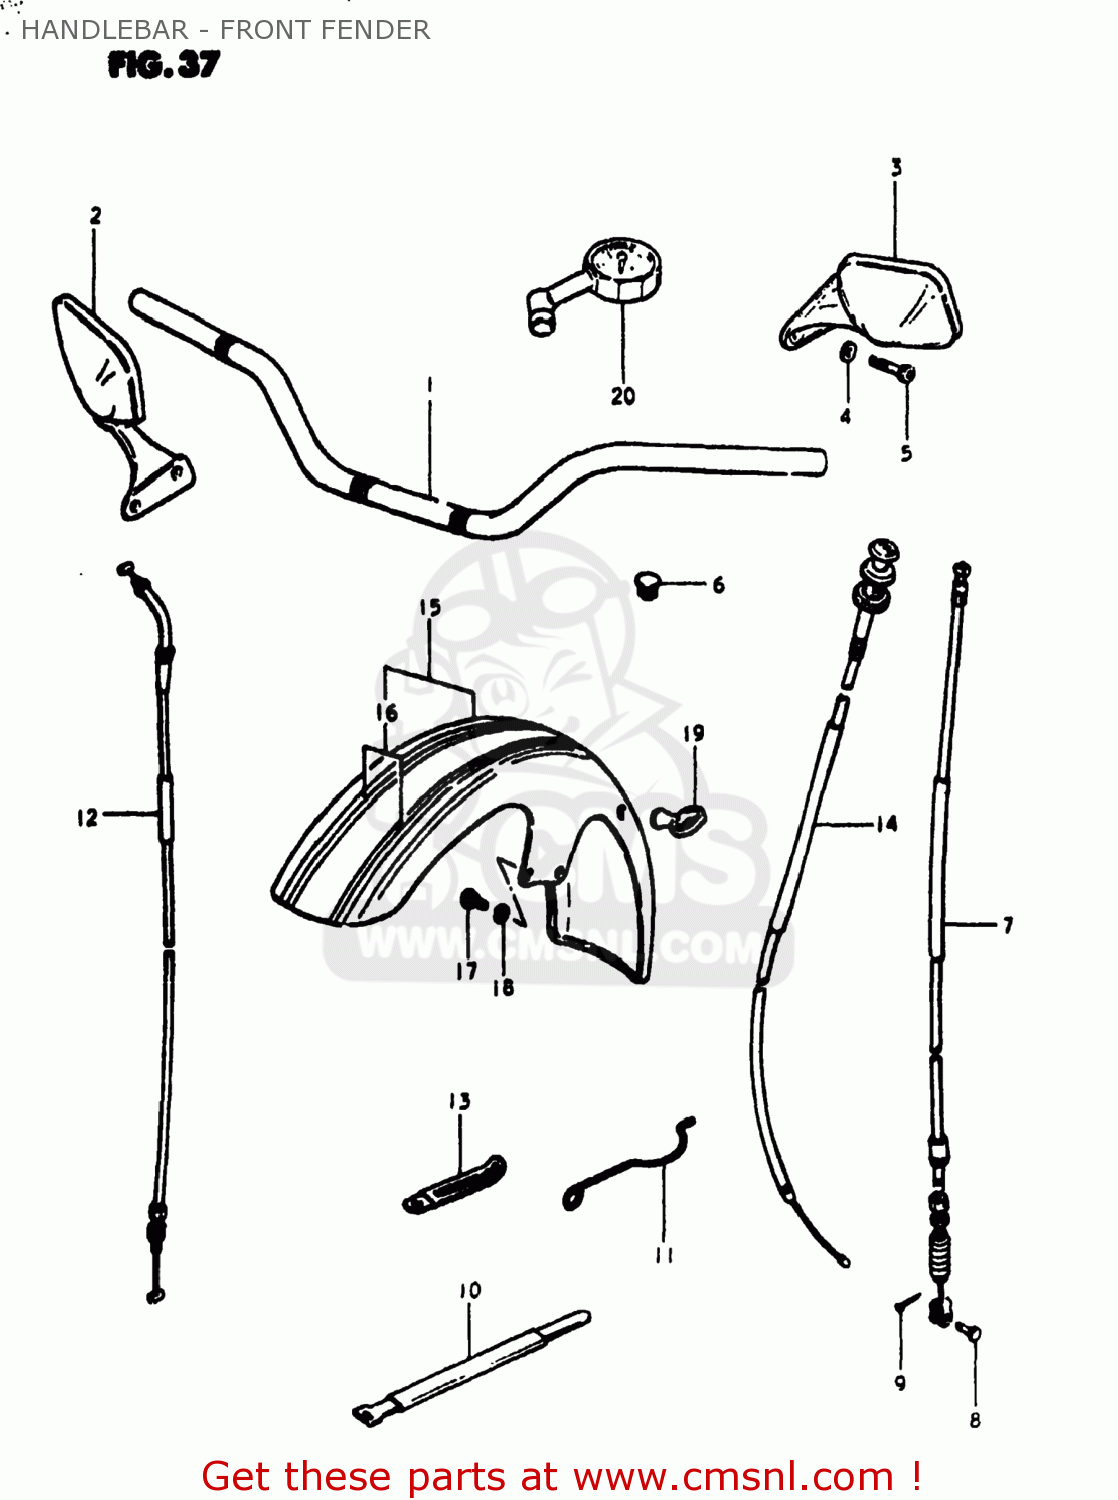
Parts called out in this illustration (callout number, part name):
1	HANDLEBAR
2	MIRROR ASSEMBLY,RIGHT
3	MIRROR ASSEMBLY,LEFT
4	WASHER,REAR VIEW MIRROR
5	BOLT
6	CAP(OD:14)
7	CABLE,CLUTCH
8	PIN(L:15)
9	PIN
10	CLAMP
11	GUIDE,CABLE
12	CABLE ASSEMBLY,THROTTLE
13	CLAMP
14	CABLE ASSEMBLY,STARTER
15	FENDER,FRONT
16	TAPE SET,FRONT FENDER STRIPE
17	BOLT
18	LOCK WASHER
19	GUIDE,CABLE
20	GAUGE ASSY,AIR PRESSURE
